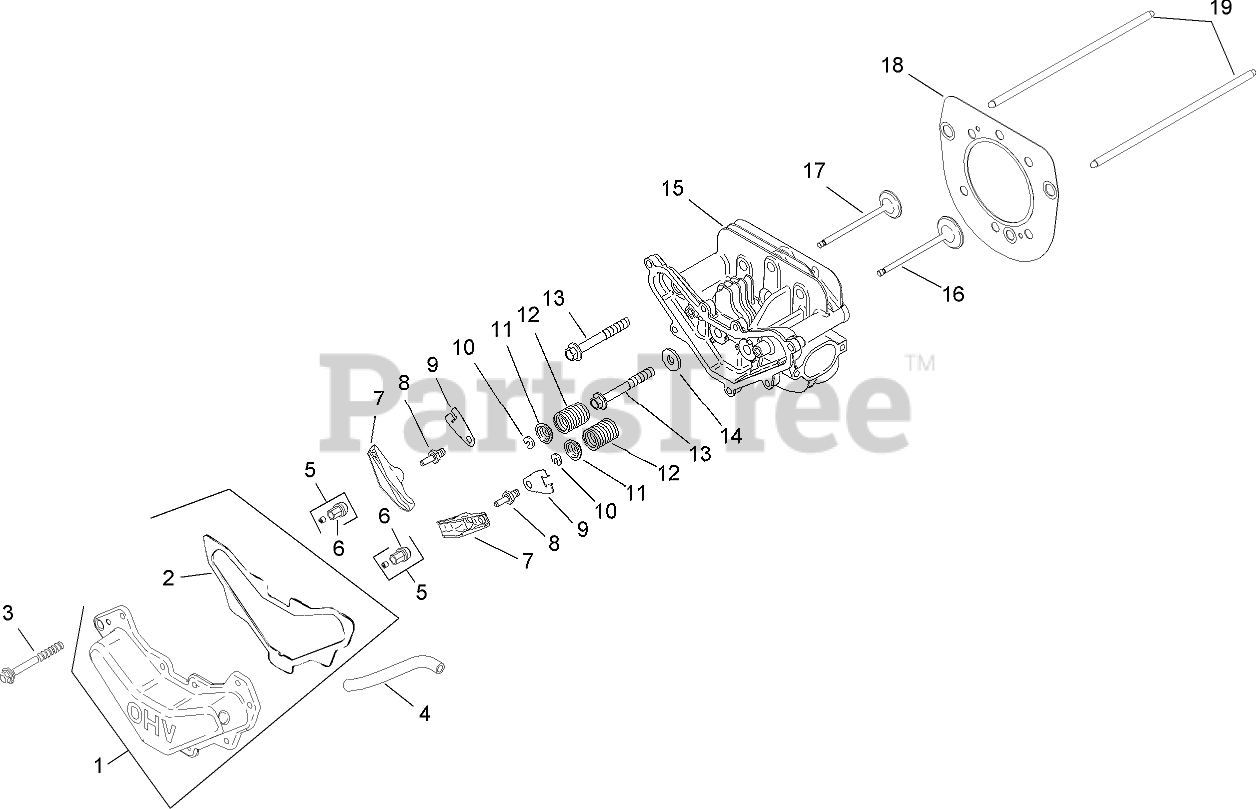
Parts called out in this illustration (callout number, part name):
1	Valve Cover Kit (Includes 2)
2	Gasket-Cover, Valve
3	SCREW-HHFTF (M6X1.0X20)
4	Hose-Breather
5	Screw-Set
6	Pivot-Arm, Rocker
7	Arm-Rocker
8	Stud-Rocker
9	Plate-Guide, Push Rod
10	Lock-Retainer
11	Cap-Spring, Valve
12	Spring-Valve
13	Screw-Flange, Hex (M10x1.5x37)
14	Washer-Flat (1/2)
15	Head-Cylinder
16	Valve-Exhaust
17	Valve-Intake
18	Cylinder Head Gasket Kit (Includes 13-14, and Part Nos. 12 041 01-S, 12 041 02-S and 20 041 07-S)
19	Rod-Push
